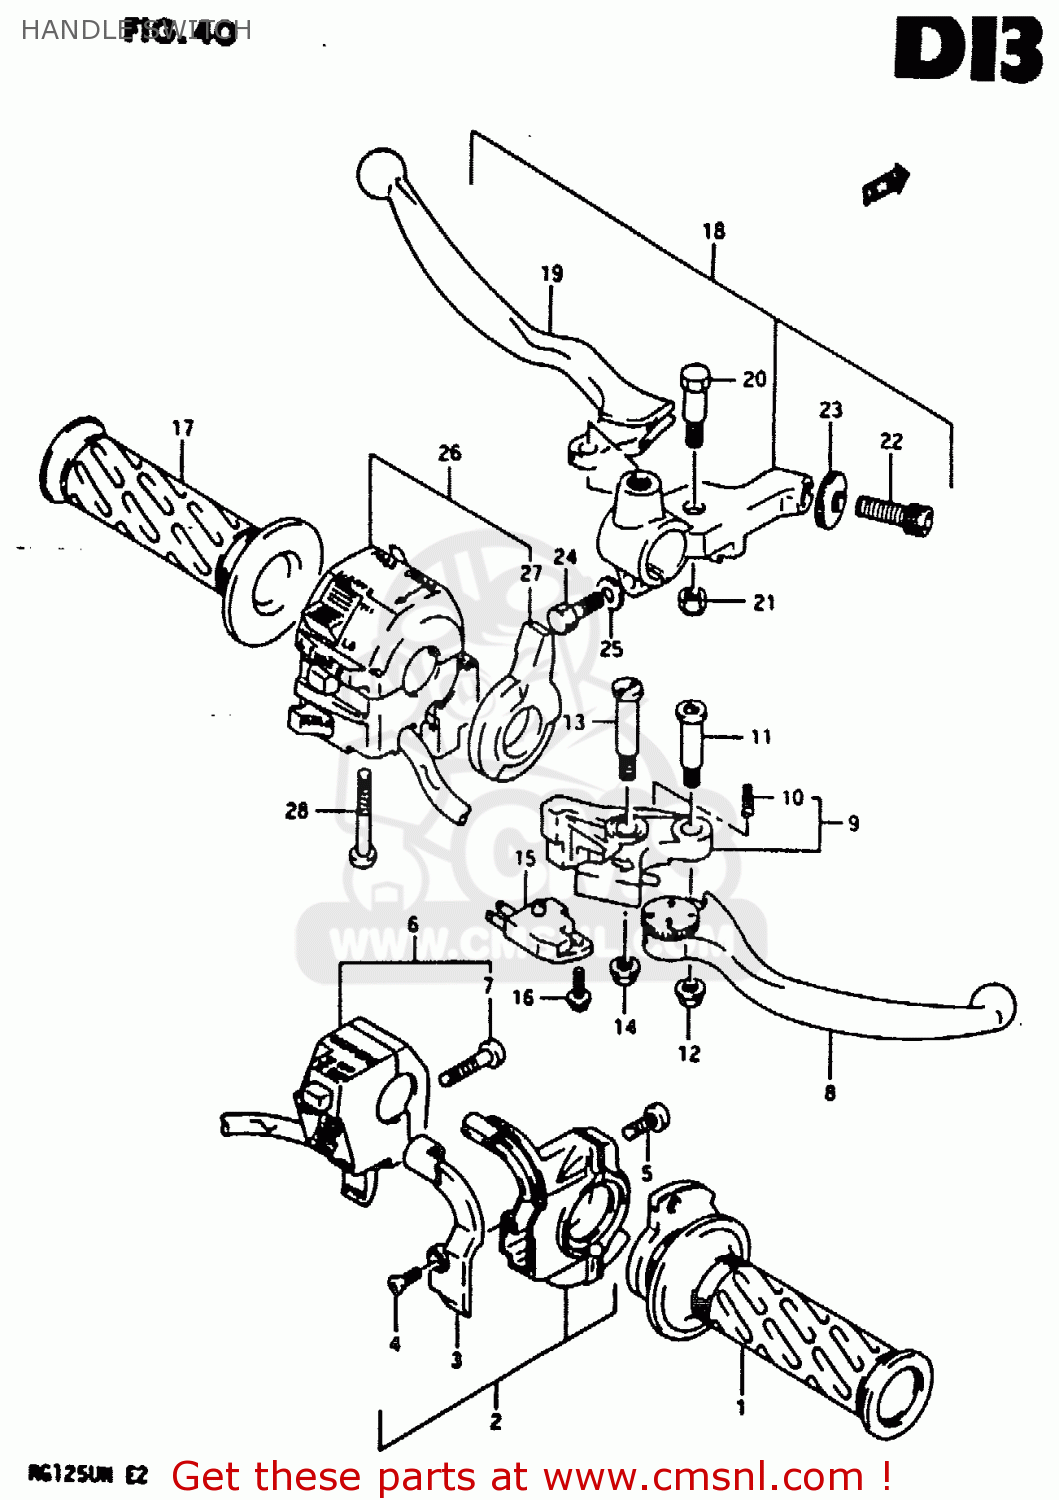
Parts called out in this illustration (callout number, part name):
1	GRIP, THROTTLE
2	CASE ASSY,THROTTLE
3	COVER,THROTTLE CASE
4	SCREW 4X10
5	SCREW
6	SWITCH ASSY,HANDLE,R
7	SCREW, 5X45
8	LEVER,ADJUST
9	KNOCKER
10	SPRING
11	BOLT,LEVER
12	NUT
13	BOLT,LEVER PIVOT
14	NUT 6MM
15	SWITCH ASSEMBLY,STOP
16	SCREW
17	GRIP,LEFT
18	LEVER ASSEMBLY,CLUTCH
19	LEVER,CLUTCH
20	BOLT,LEVER
21	NUT
22	ADJUSTER,CABLE
23	NUT,CABLE ADJUSTER
24	BOLT
25	WASHER
26	SWITCH ASSEMBLY,HANDLE,LEFT
27	LEVER,CHOKE
28	SCREW, 5X45
